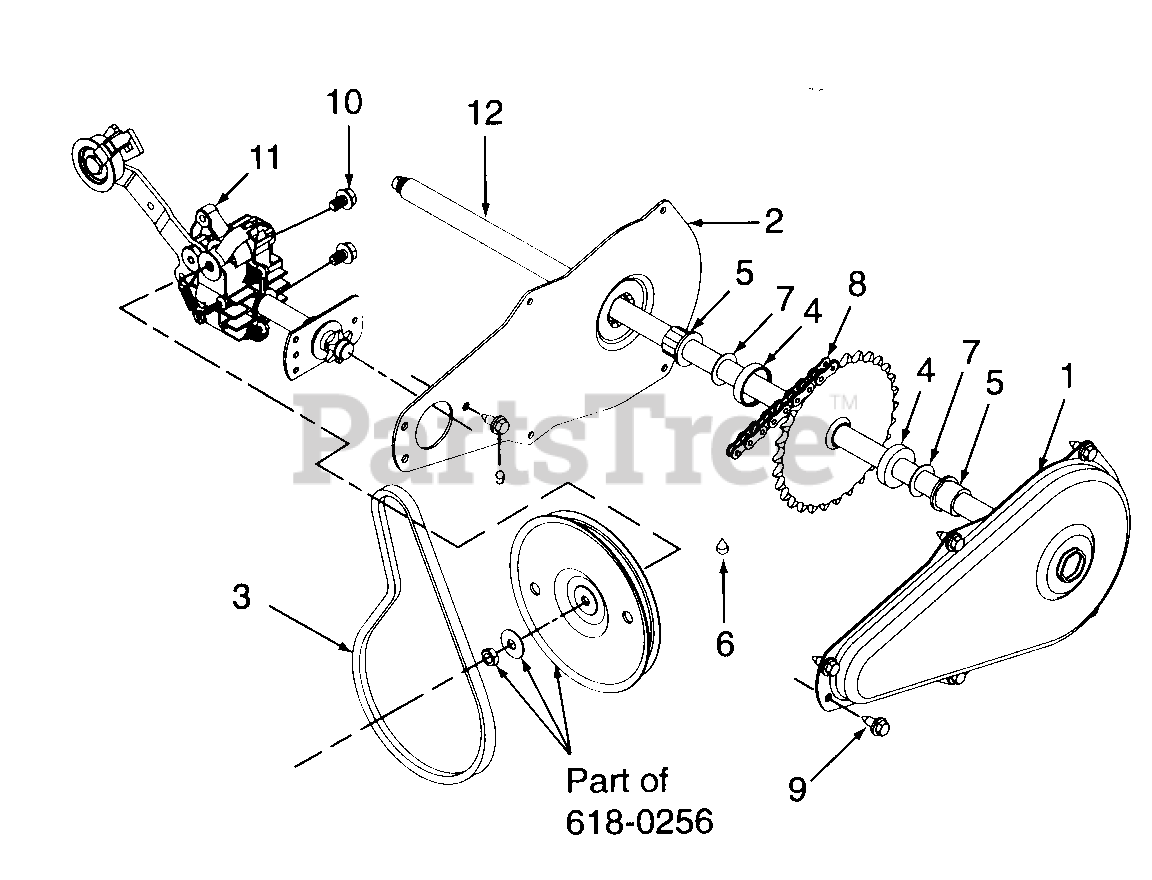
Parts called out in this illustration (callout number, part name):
1	Chain Case LH
2	Chain Case RH
3	V-Belt, 3/8 x 24.68
4	Spacer, .630 x 1.25 x .29
5	Bearing, Hex Flange, .631 ID
6	Grease, Benalene
7	Washer, Flat, 5/8 x 1.0
8	Chain, Endless, #41 x 50 Lnks
9	Screw, Hex Wash Hd, 1/4-14 x .625
10	Screw, Hex Wash Hd Tapp 5/16-18 x .50
11	Complete Transmission Ass'y
12	Shaft Assembly, Axle
